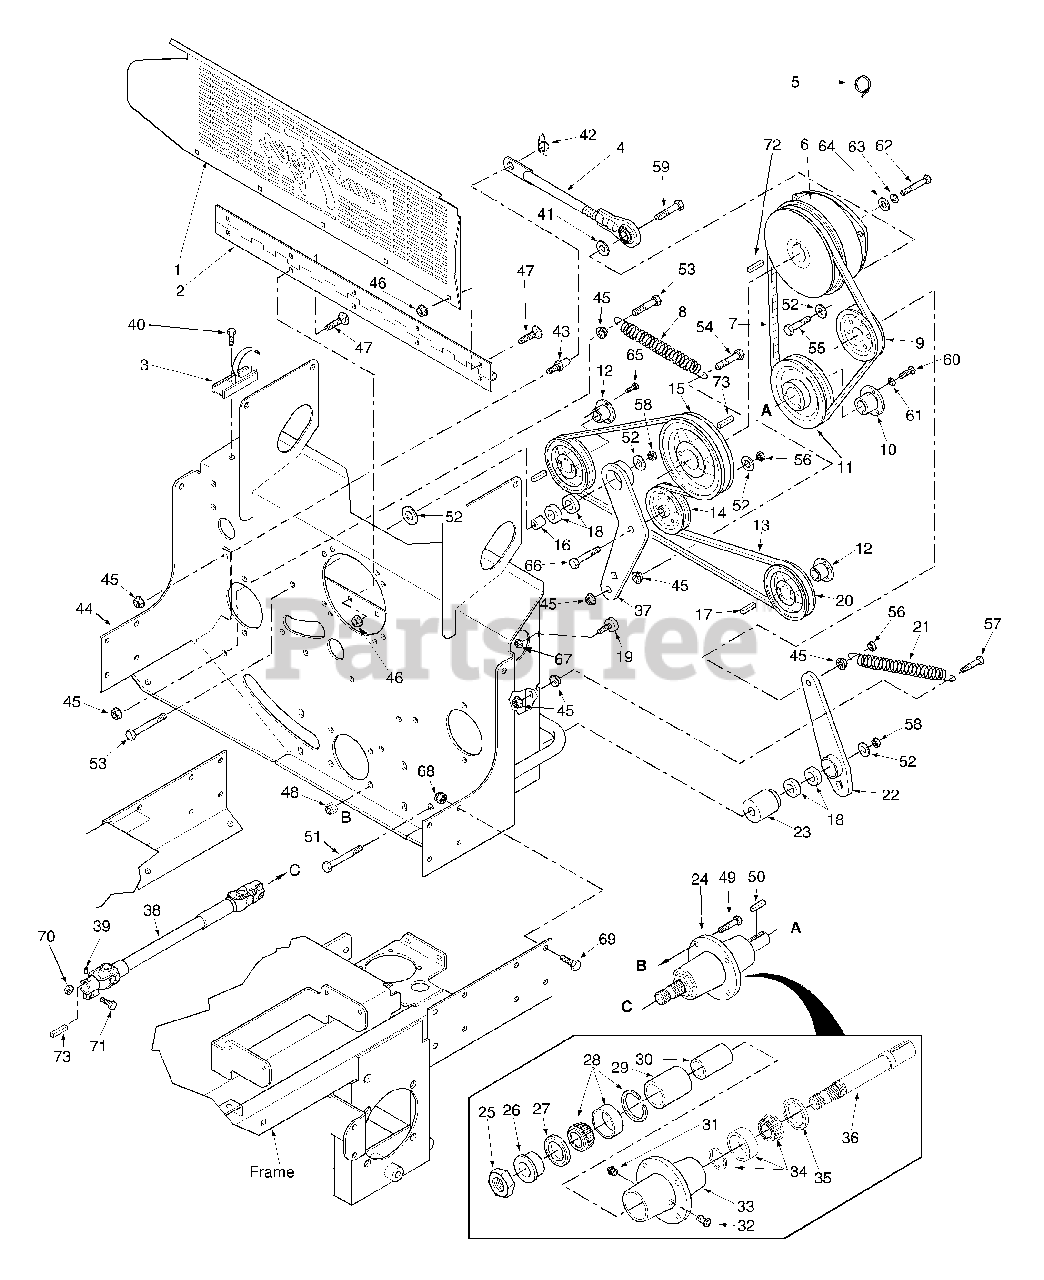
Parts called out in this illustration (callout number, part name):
1	Belt Guard, Rear
2	Hinge, Belt Guard
3	Latch, Hood
4	Rod Assembly, Clutch Anti-Rotation
5	Clamp, Cable
6	Clutch, Ogura GT-3.5
7	Belt, Deck Drive
8	Spring, Transmission Idler
9	Pulley, Idler 5" Dia.
10	Tapered Hub, 1" Bore
11	Pulley, 6.70 Tapered Bore
12	Tapered Hub, 17mm Bore
13	Belt, Pump Drive STT
14	Pulley, Idler 4" Dia.
15	Pulley, 4.25 Dia. - 1.125 Bore
16	Spacer, Idler Bearing
17	Key, 5.0 x 5.0 x 25mm
18	Ball Bearing
19	Bumper, Rubber
20	Pulley, 6.25 OD Tapered Bore
21	Spring, PTO
22	Idler Arm Weldment, PTO Drive
23	Pivot, Idler PTO
24	Spindle Assembly, Deck Drive
25	Nut, 1.06-18 Thread
26	Spindle Bushing, Bottom
27	Seal, 2.0 OD x 1.625 Bore
28	Roller Bearing Tapered
29	Spacer, Outside
30	Spacer, Inside
31	Grease Fitting, 1/4-28
32	Relief Fitting
33	Spindle Housing
34	Roller Bearing Tapered
35	Seal, 2.0 OD x 1.5 Bore
36	Shaft, Deck Drive
37	Idler Arm Weldment, Pump Drive
38	Driveshaft (Air Cooled Engine)
39	Set Screw, 3/8-16 x 3/4" Torx Socket
40	Screw, #10-32 x .56
41	Flatwasher, 3/8-.391 x .938 x .105
42	Pin, Rue Cotter 3/8 Dia.
43	Stud, Anti Rotation
44	Pump Mounting Plate Weldment (Air Cooled)
45	Nut, Serrated Flange 3/8-16
46	Nut, Serrated Flange 1/4-20
47	Bolt, Carriage 1/4-20 x 1/2"
48	Nut, Elastic Stop 5/16-18 Grade 8
49	Bolt, Hex Head 5/16-18 x 1-3/4" Grade 8
50	Key, 1/4 x 1/4 x 1-1/2"
51	Bolt, Hex Head 3/8-16 x 4-1/2" Grade 8 Black
52	Washer, 3/8 Hardened
53	Bolt, Hex Head 3/8-16 x 1-3/4" Grade 8 Black
54	Bolt, Hex Head 3/8-16 x 1-1/2" Grade 8 Black
55	Bolt, Hex Head 3/8-16 x 2-1/2" 1.5 Thread Grd.8
56	Nut, Center Lock 3/8-16
57	Bolt, Hex Head 3/8-16 x 1-1/2" Grade 8 Black
58	Nut, Elastic Stop 3/8-16
59	Bolt, Hex Head 3/8-16 x 2"
60	Bolt, Hex Head 1/4-20 x 1-3/8"
61	Lockwasher, 1/4 Spring
62	Bolt, Hex Head 7/16-20 x 2-1/2" UNF
63	Lockwasher, 7/16 Spring
64	Flatwasher, 7/16-.469 x 1.75 x .25
65	Bolt, Hex Head 1/4-20 x 1" Grade 8
66	Bolt, Hex Head 3/8-16 x 1-3/4"
67	Nut, Serrated Flange 5/16-18
68	Nut, Elastic Stop 3/8-16
69	Bolt, Hex Head 3/8-16 x 1"
70	Nut, Center Lock 3/8-16
71	Bolt, Hex Head 3/8-16 x 1-3/4"
72	Key, 1/4 x 1/4 x 2-1/4"
73	Key, 1/4 x 1/4 x 1"
